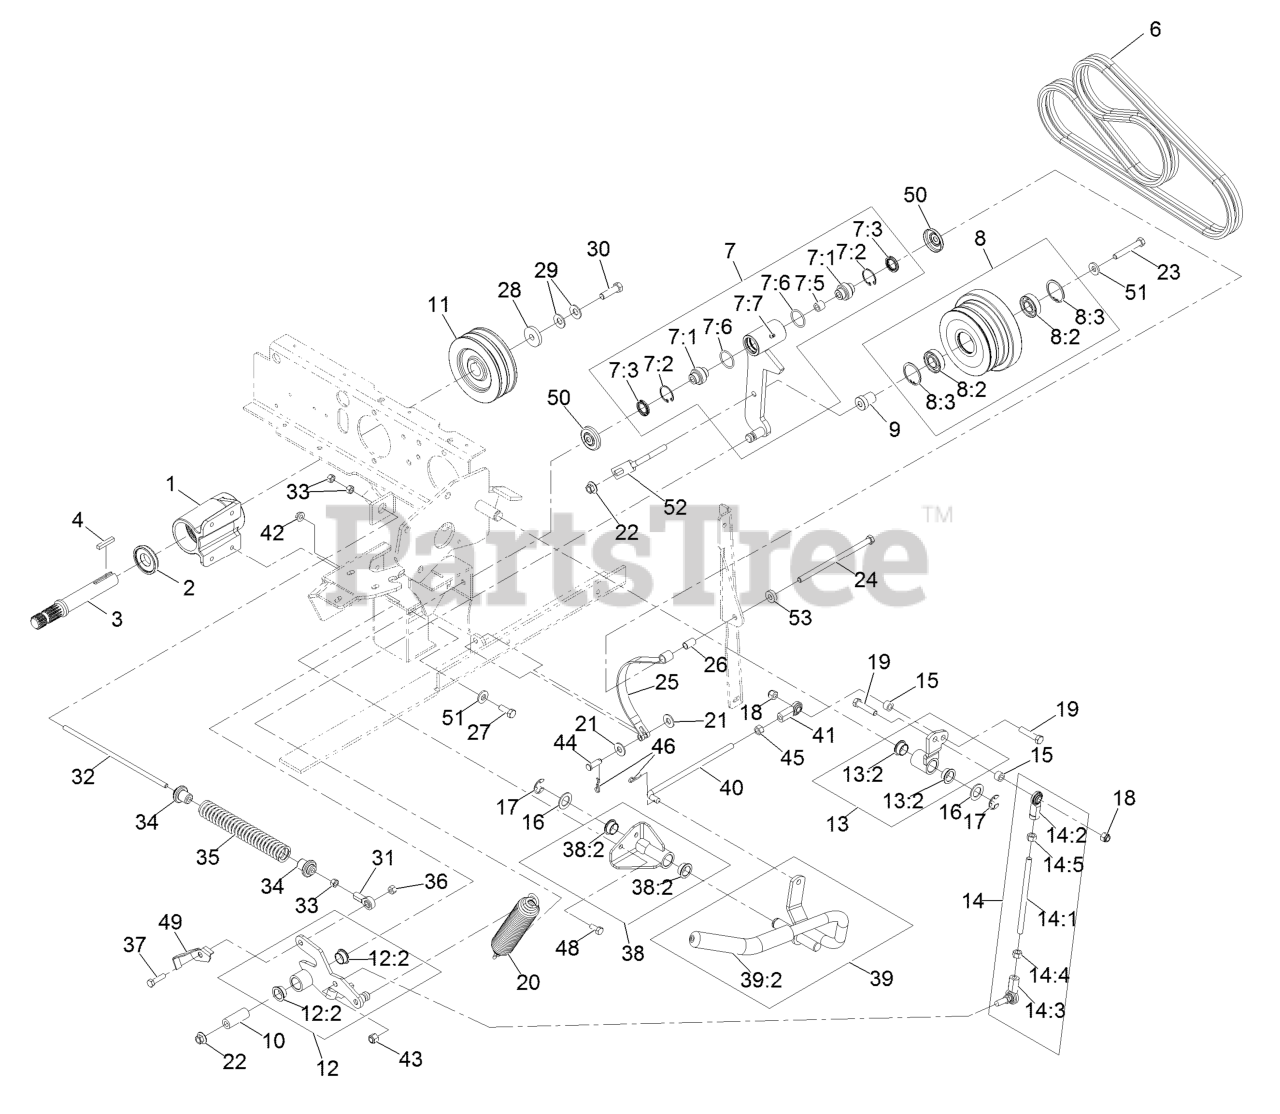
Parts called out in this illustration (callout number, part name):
2	SPACER-GUARD, BOTTOM
3	SHAFT-JACK
4	KEY-SQUARE
6	BELTS-MATCHED PAIR
7	IDLER PIVOT ASM
7:1	BEARING-SPHERICAL
7:2	RING-SNAP
7:3	SEAL-LIP, SINGLE
7:5	BUSHING-LEVER, LIFT
7:7	FITTING-GREASE
8	IDLER SHEAVE ASM
8:2	BEARING-BALL
8:3	RING-RETAINING
9	SPACER-IDLER
10	BUSHING
12	ARM ASM
12:2	BUSHING-BRONZE
13	ARM ASM
13:2	BUSHING-BRONZE
14	CLUTCH LINK ASM
14:1	ROD-LINKAGE
14:2	JOINT-BALL END, LH
14:3	BALLJOINT-RH
14:4	NUT-HEX
14:5	NUT-HEX, LH
18	NUT-LOCK, NI
19	SCREW-HH
20	SPRING-EXTENSION
21	WASHER-FLAT
23	BOLT-CARR
24	SCREW-HH
25	BAND-BRAKE
27	SCREW-HH
28	WASHER-CLUTCH
29	WASHER-SPRING
30	SCREW-HH
31	BALLJOINT-RH
32	LINKAGE-ROD, PTO BRAKE
33	NUT-HEX
34	BUSHING-SPRING
35	SPRING-BRAKE
36	NUT-LOCK, NI
37	SCREW-HH
38	PIVOT ASM
38:2	BUSHING-BRONZE
39	PTO HANDLE ASM
39:2	GRIP-LEVER, CONTROL
40	LINK-HANDLE
41	JOINT-BALL, END
43	NUT-LOCK
44	PIN-CLEVIS
45	NUT-HEX
46	PIN-COTTER
48	SCREW-HH
49	SWITCH-FLAG
50	GUARD-TOP
51	WASHER-BELLEVILLE
52	GUIDE-BELT
53	SPACER
